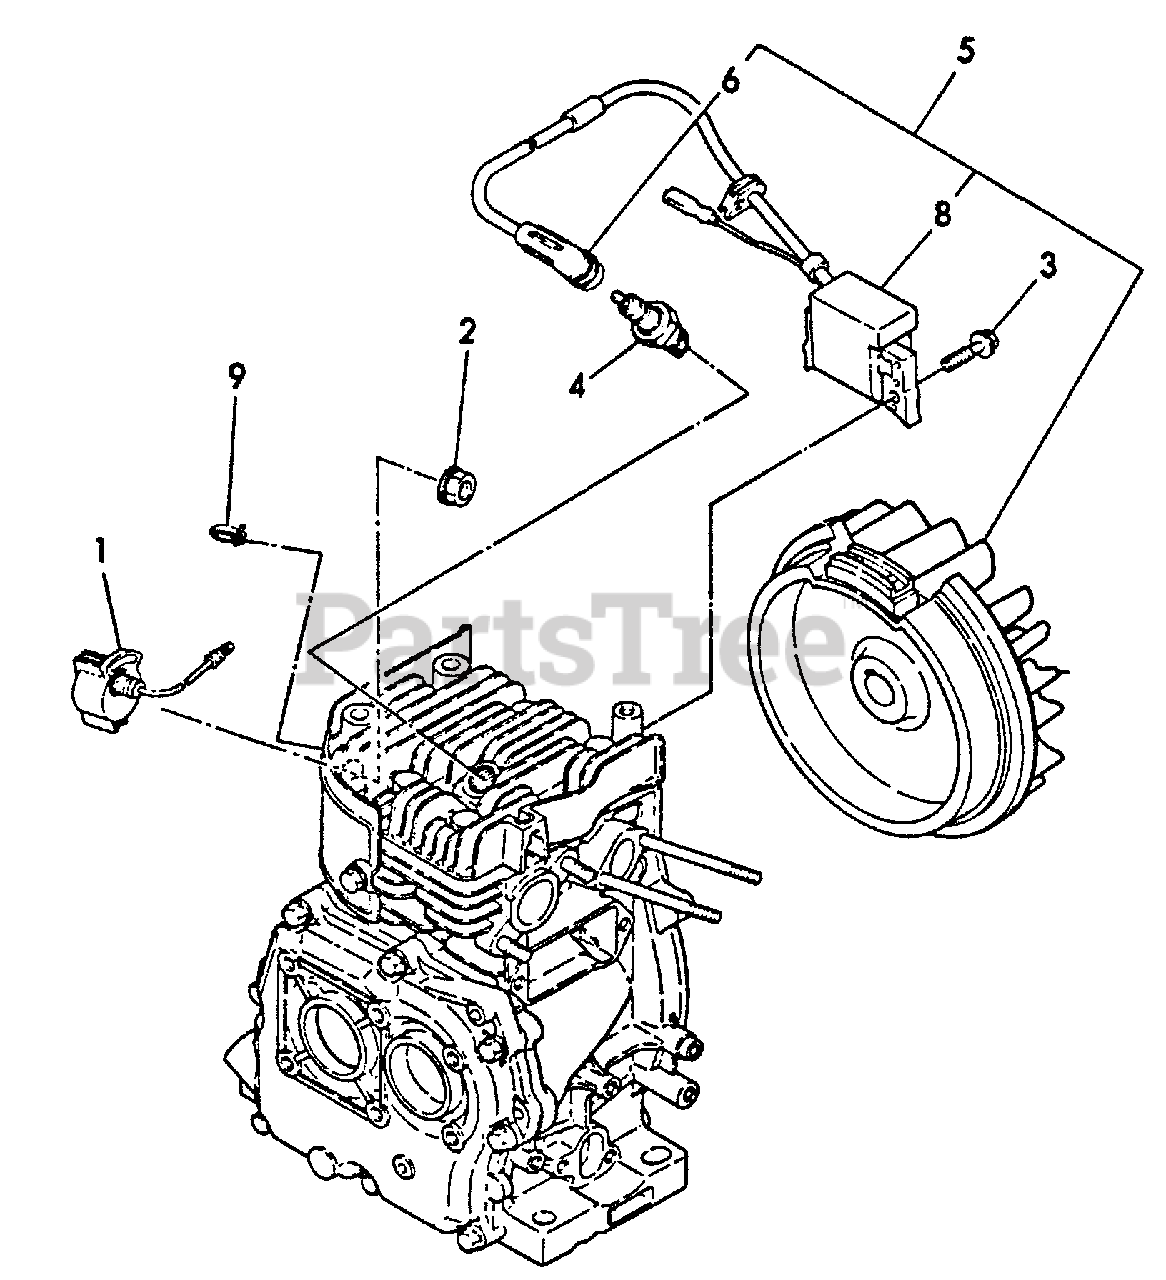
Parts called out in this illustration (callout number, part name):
1	IGNITION SWITCH ASSY
2	U-NUT M8
3	BOLT - 6×30
4	SPARK PLUG
5	FLYWHEEL
6	CAP, PLUG
8	COIL, IGNITION
9	CLAMP
